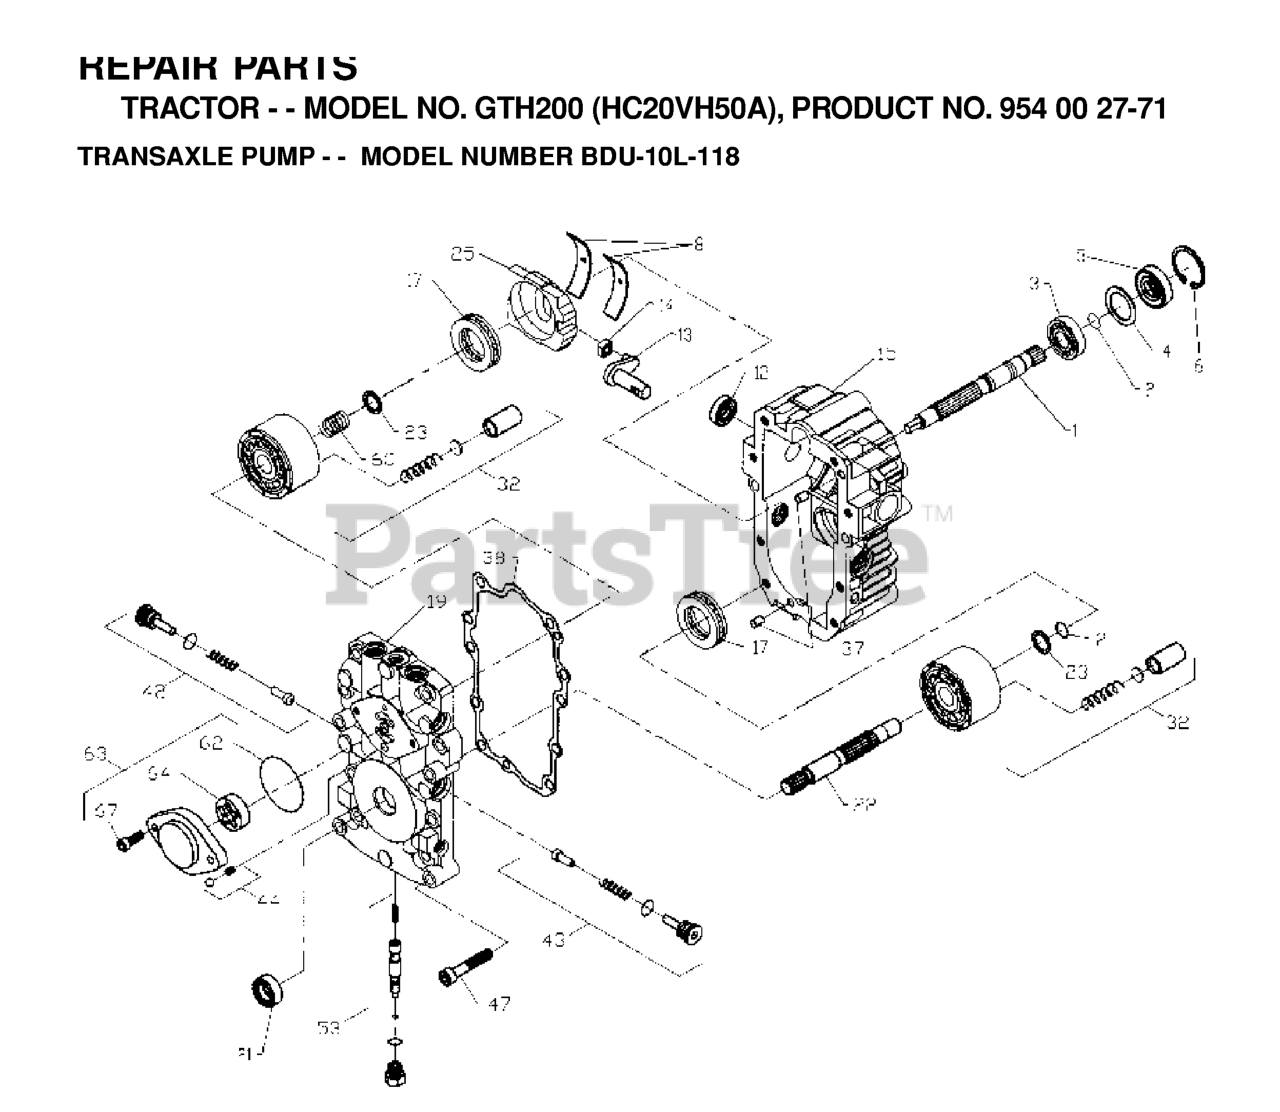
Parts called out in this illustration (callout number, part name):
1	SHAFT, PUMP
2	RETAINIANG RING
3	BALL BEARING 2003043
5	SEAL LIP
6	RETAINING PIN
8	CRADLE BEARING
13	TRUNION ARM
14	GUIDE 2000015 HYD
15	HOUSING KIT, TRANSMISSION
17	BALL BEARING
19	CENTER SECTION KIT
21	LIP SEAL 9008000-0127
22	SHAFT MOTOR 2003034
25	SWASHPLATE,VARIAB
38	GASKET 2003060
42	CHECK VALVE KIT 2510050
43	CHECK VALVE KIT 2510050
44	CHARGE RELIEF KIT 2510011
53	KIT,BYPASS VALVE(2513011)
62	O-RING.HYDRO GEAR.9004101-1340
63	CHARGE PUMP KIT
64	GEROTOR ASSEMBLY
67	SCREW, SOCKET HEAD CAP
